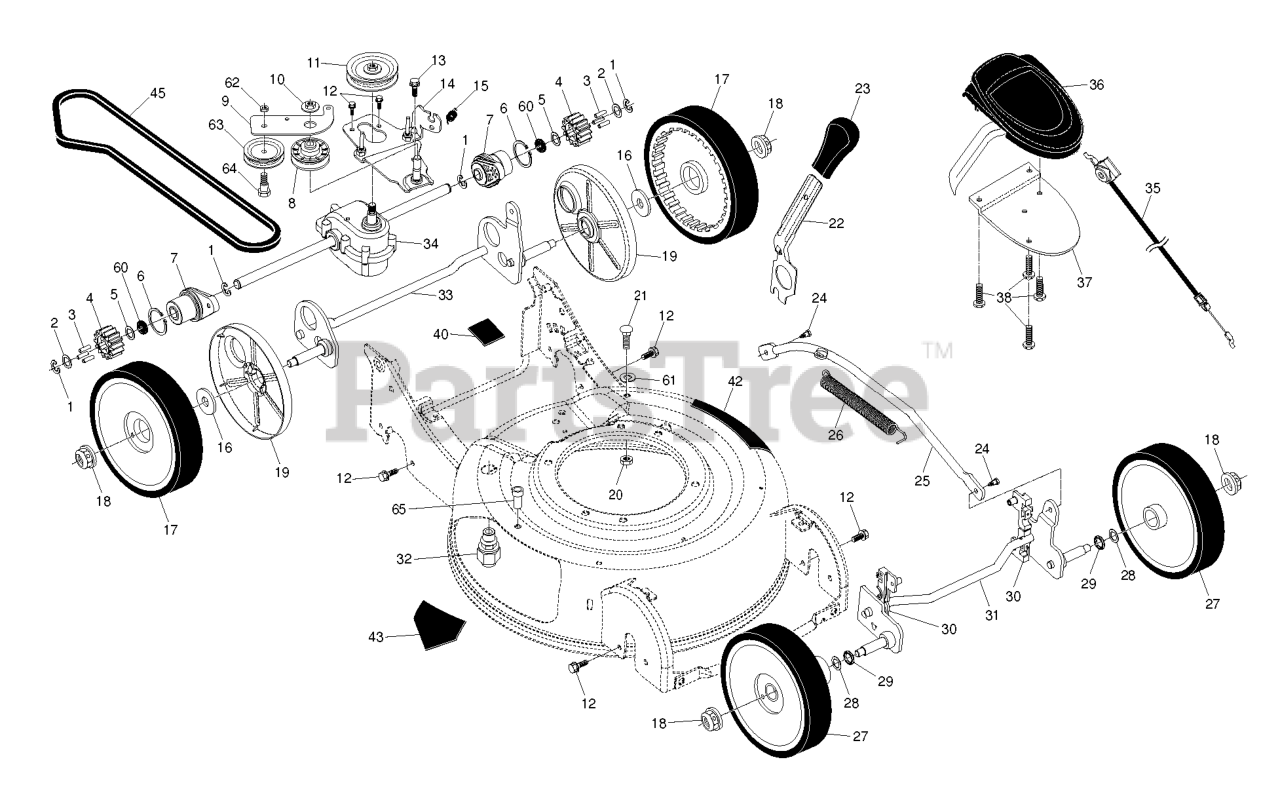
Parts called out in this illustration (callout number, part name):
1	E-RING 7/16 RE
2	THRUST WASHER
3	PAWL.DRIVE.ETCHED
4	PINION.DRIVE.WALK
5	WASHER
6	RETAINING RING (2 2)(3 2)
7	BEARING.ASM
8	PULLEY.IDLER.V-BELT
9	ARM.IDLER.BZP
10	NUT.HEX.FLANGE.3/8-16.LOCKNUT
11	PULLEY.1.PIECE
13	SCREW 14-20 X 5/8
15	SPRING.RETURN
16	WASHER FLUT
17	WHEEL.8X1.75.H3SPK.RAD3.GY.BU3
18	NUT.HEX.FLANGE.3/8-16.LO(3 2)
19	COVER.DUST.WHEEL
20	NUT, HEX
21	BOLT.CARRIAGE.1/4-20 X 7/8
24	SHOULDER BOLT SEMI GIMLET PT.
25	ROD.LIFT.PNT
26	SPRING EXTENSION
27	WHEEL & TIRES ASSY, FRONT
28	WASHER.FLAT.1/2
29	O-RING..070X.487.NEOPRENE
30	BUSHING.FRONT.TORQUE.SHAFT
37	BRACKET.DRIVE.CONTROL.MOUNT.BL
38	SCREW, PHILLIPS HEAD 10 X 5/8
43	DECAL.INTERNATIONL.CUTFINGER
61	LOCKWASHER
62	NUT.CENTERLOCK.5/16-
63	IDLER PULLEY
64	SHOULDER BOLT
